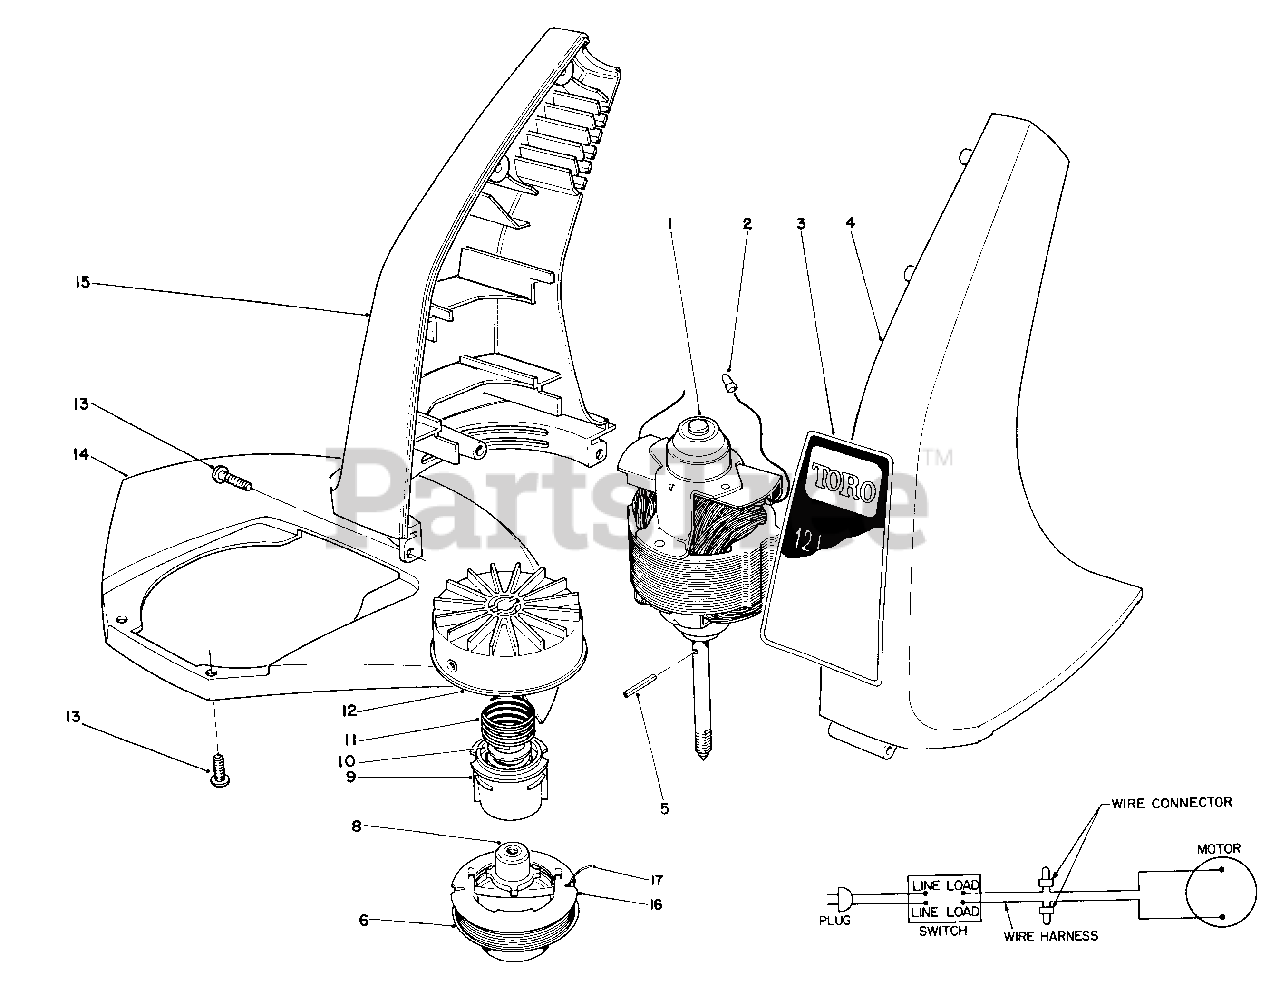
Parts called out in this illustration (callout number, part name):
2	Connector-Wire
3	Decal-12 Inch
4	Housing-L.H.
6	50 Ft. .065 Dia. Cutting Line Prewound on Spool
12	Drum w/Eyelet
13	Screw
15	Housing-R.H.
16	Empty Spool
17	50 Ft. Coil-.065 Dia. Cutting Line in Coil
